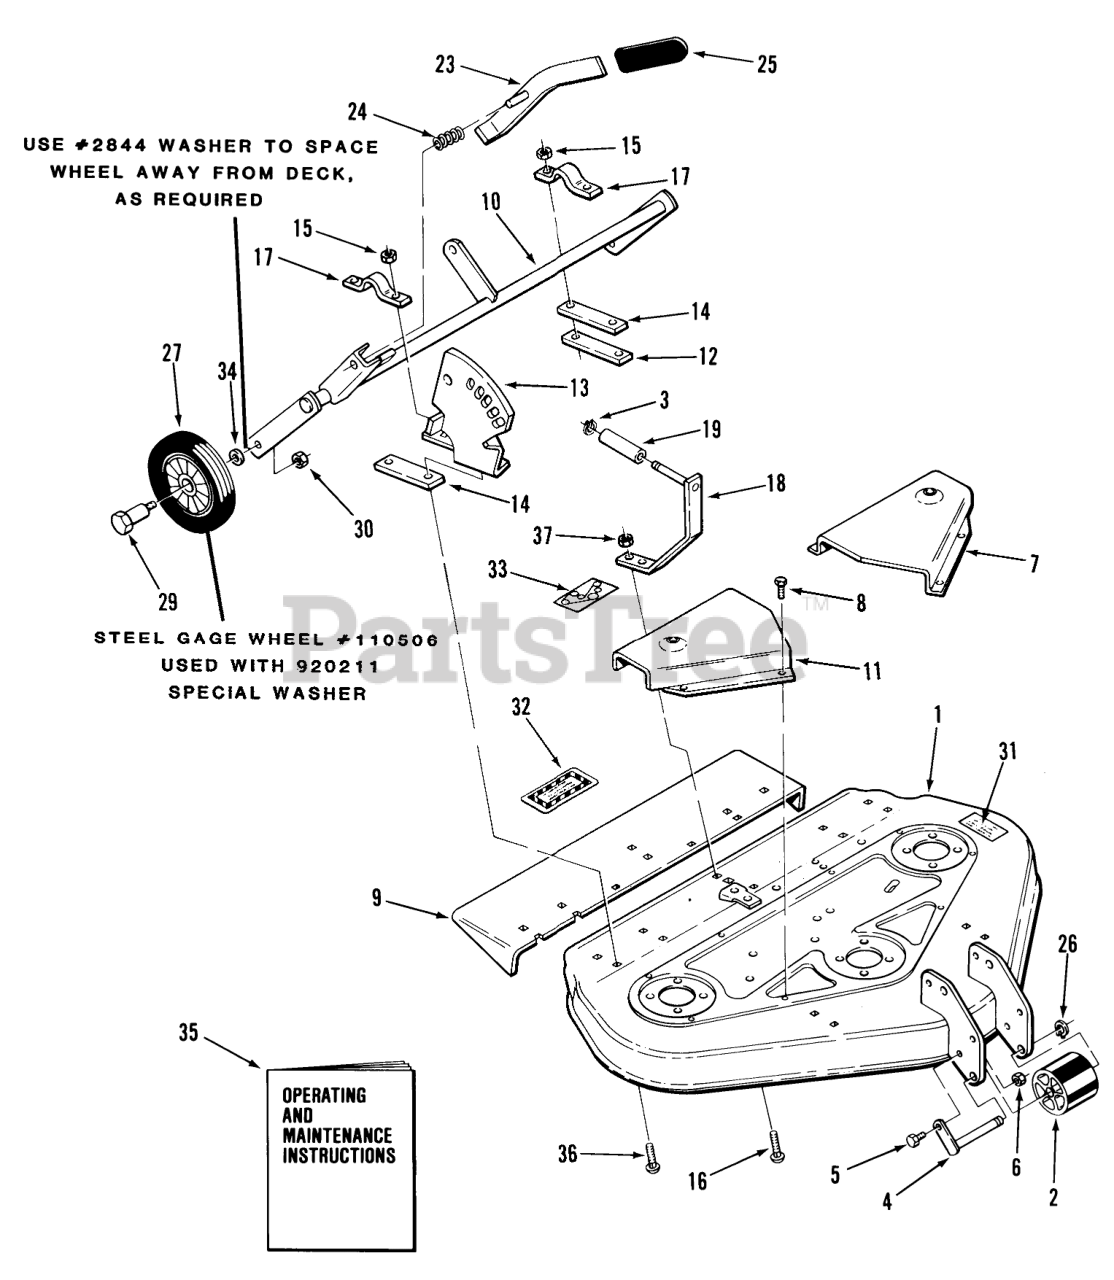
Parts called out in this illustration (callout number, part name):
1	ASSY-MOWER DECK 3 R
2	Roller
3	Snap Ring
4	Roller Shaft
5	H H C S
6	Nut
7	Cover-Belt
8	Bolt
9	Chute Extension
10	ASSY GAGE WHEEL S R
11	Belt Cover RH
12	Strap
13	Quadrant
14	Strap 1/16
15	Nut
16	Bolt
17	CLAMP
18	BRACKET ASSY R
19	SPACER
23	Lever
24	SPRING-COMPRESSION
26	Retaining Ring
27	Wheel 6 x 1.75
29	BOLT-SHOULDER
30	Nut
31	Caution Decal
32	Decal-Caution
33	DECAL-HEIGHT BELT
34	WASHER
35	Operating and Maintenance Instructions
36	Bolt-Carriage
37	Nut
